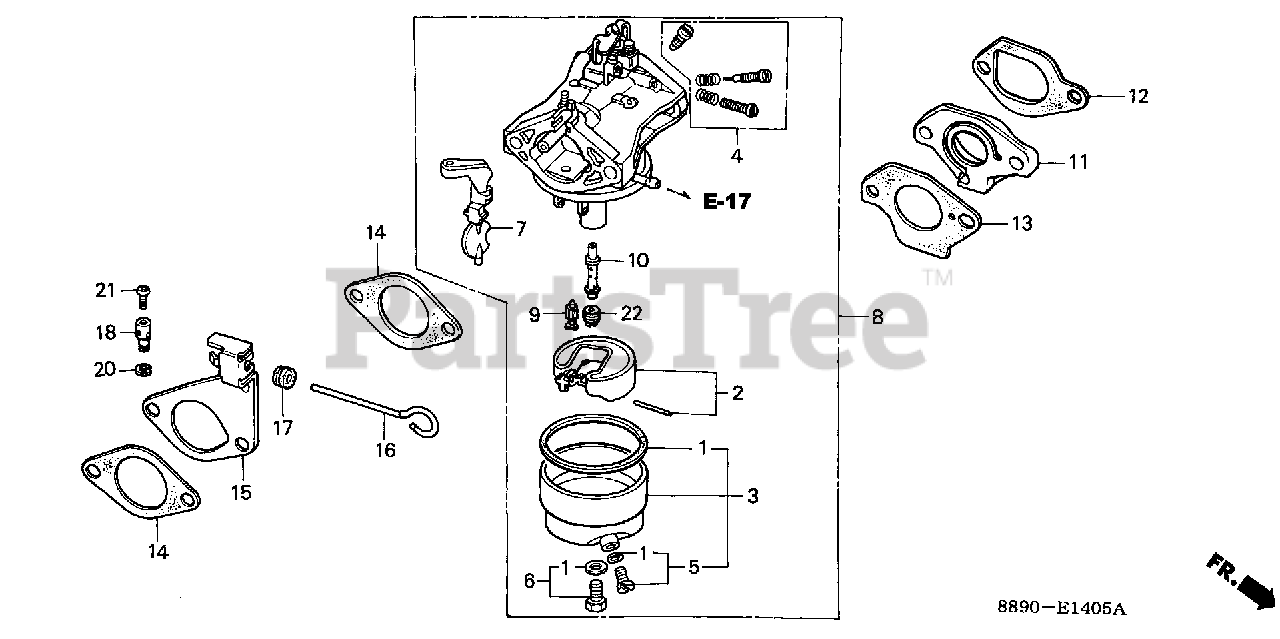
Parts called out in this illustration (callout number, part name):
1	GASKET SET (CARBURETOR NO.)
2	FLOAT SET (CARBURETOR NO.)
3	CHAMBER SET, FLOAT (CARBURETOR NO.)
3	CHAMBER SET, FLOAT (CARBURETOR NO.) (NOT AVAILABLE)
4	SCREW SET A (CARBURETOR NO.)
4	SCREW SET A
5	SCREW SET, DRAIN (CARBURETOR NO.)
6	SCREW SET (CARBURETOR NO.)
6	SCREW SET
6	SCREW SET B (CARBURETOR NO.)
7	CHOKE SET (CARBURETOR NO.)
8	CARBURETOR ASSY. (BB33C D)
9	VALVE, FLOAT (CARBURETOR NO.)
10	NOZZLE, MAIN (CARBURETOR NO.)
11	INSULATOR, CARBURETOR
12	GASKET, INSULATOR
13	GASKET, CARBURETOR
14	GASKET, AIR CLEANER
15	STAY, CHOKE CONTROL (NOT AVAILABLE)
16	ROD, CHOKE CONTROL (NOT AVAILABLE)
17	GROMMET, CHOKE ROD
18	HOLDER, CABLE
20	CIRCLIP (5MM)
21	SCREW, PAN (4X8)
22	JET, MAIN (#75) (CARBURETOR NO.)
22	JET, MAIN (#78) (CARBURETOR NO.)
22	JET, MAIN (#80) (CARBURETOR NO.)
22	JET, MAIN (#82) (CARBURETOR NO.)
22	JET, MAIN (#85) (CARBURETOR NO.)
